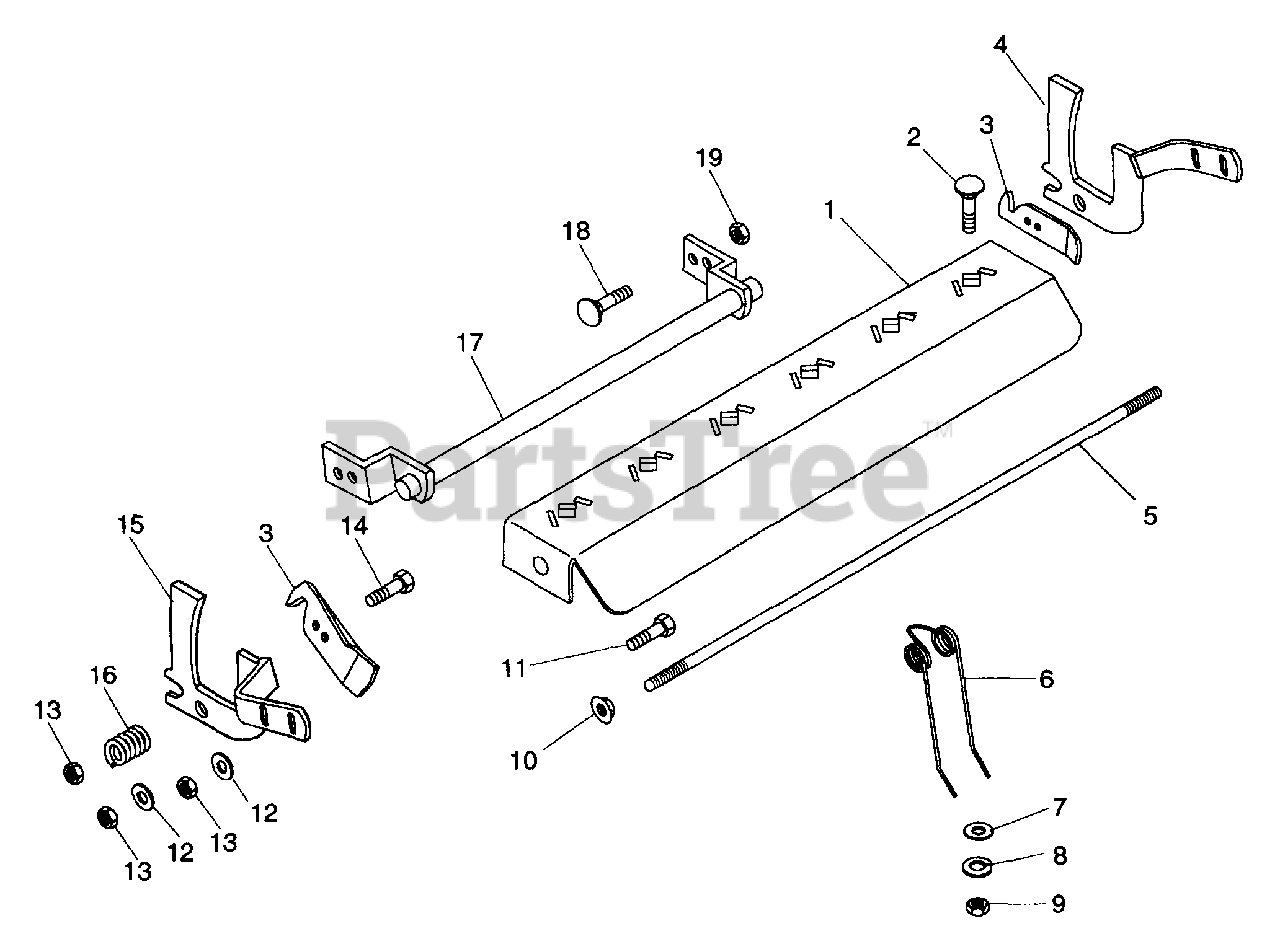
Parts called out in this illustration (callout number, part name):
1	TINE PLATE
2	BLT-RDHDSQNK .31-18X.75 SHT PL
3	AXLE LOCK
4	CAM BRACKET LH
7	WSHR-FL-STL .328X1.0X.094 PL
8	WSHR-LK .312X.097 PL HVY
9	NUT-HEX .312-18
10	NUT-LK-FLG .250-20 PL
11	BLT-HEX .25-20X.75 PL GR2
12	WSHR-FL-STL.281X.62X.065 PL
13	NUT-LK-CTR .250-20 PL
14	BLT-HEX .25-20X1.25 PL GR5
15	CAM BRACKET RH
16	SG-COMP .058X.68X.75
17	DETHATCHER RETAINER WELDMENT
18	BLT-RDHDSQNK .312-18X.62SHTPL
19	NUT-LK .312-18 GR A PL
